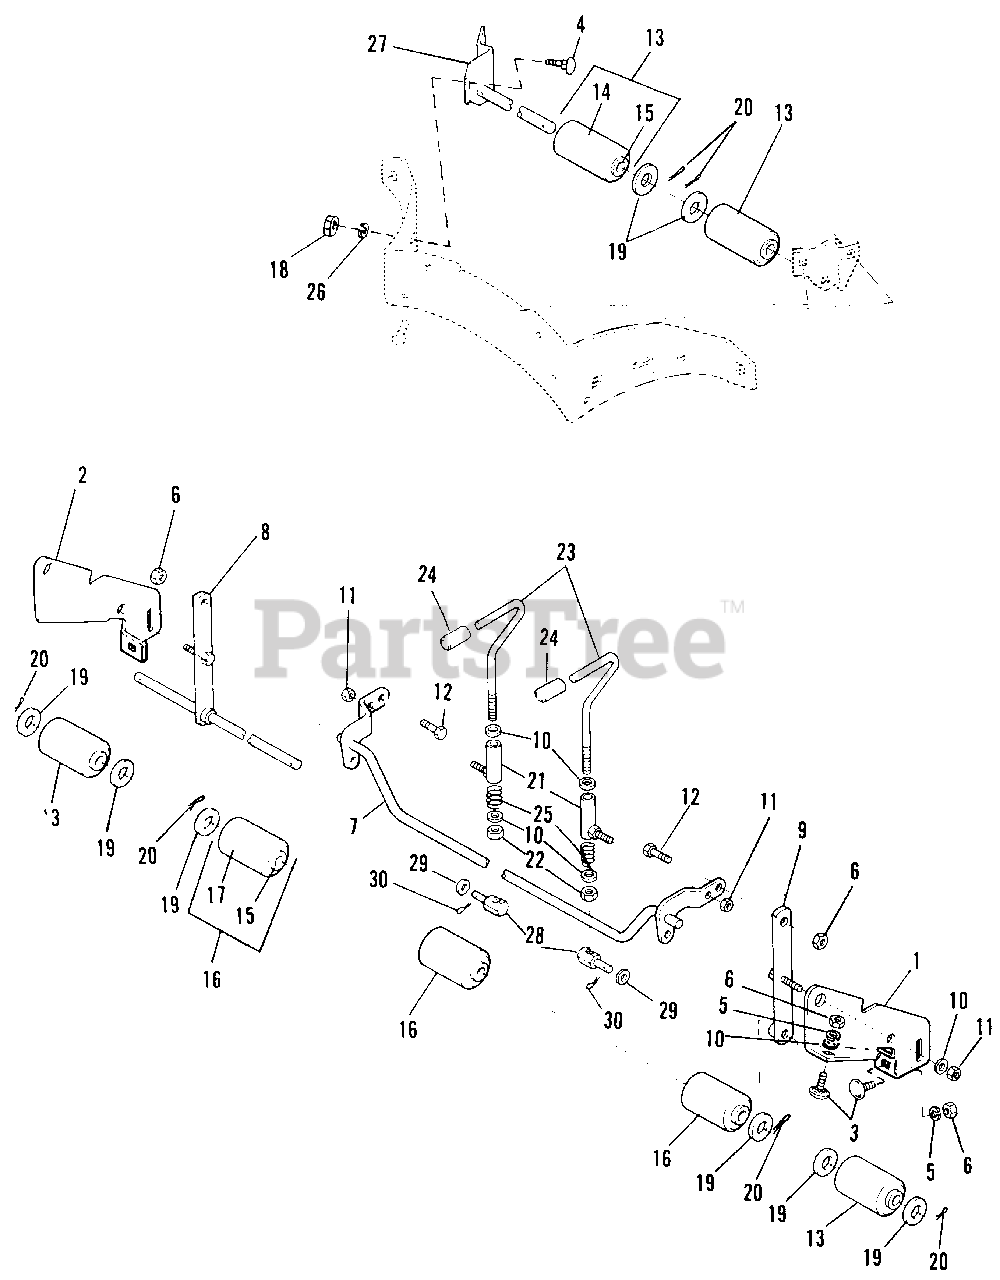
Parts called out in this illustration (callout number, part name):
1	BRACKET, Roller, L.H.
2	BRAKCET, Roller, R.H.
3	CARRIAGE BOLT, 3/8-16 x 3/4
4	CARRIAGE BOLT, 5/16-18 x 3/4
5	LOCKWASHER, 3/8
6	NUT, Hex Full, 3/8-16
7	ROCKER ARM ASSY
8	SHAFT ASSY, Roller
9	BAR ASSY, Roller
10	WASHER, Plain, 3/8
11	NUT, Hex Full Lock, 3/8-16
12	CAPSCREW, Hex Hd., 3/8-16 x 1
13	ROLLER ASSY
14	ROLLER
16	ROLLER ASSY
17	ROLLER
18	NUT, Hex Full, 5/16-18
19	WASHER, Plain, 5/8
20	PIN, Cotter, 3/16 x 1
21	SOCKET ASSY
22	NUT, Hex Jam, 3/8-16
23	HANDLE, Adjusting
24	GRIP
26	LOCKWASHER, 5/16
27	BRACKET & SHAFT ASSY
29	WASHER, Plain, 5/16
30	PIN, Cotter, 3/32x 5/8
